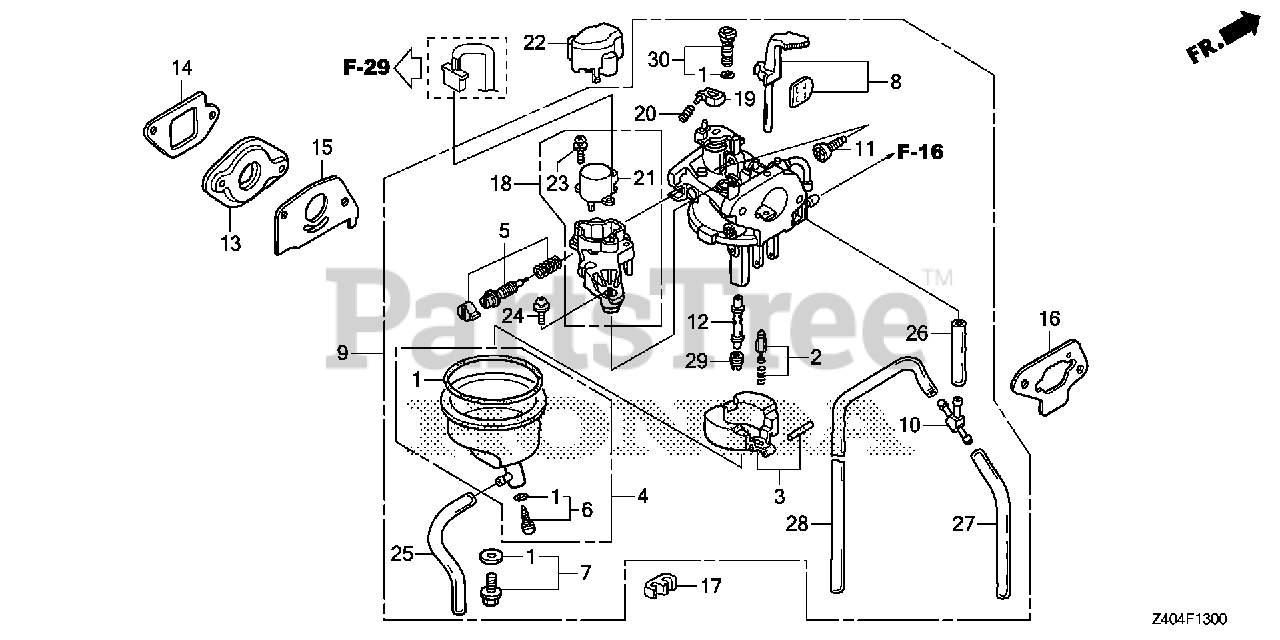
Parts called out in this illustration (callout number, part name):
1	GASKET SET (CARBURETOR NO.)
2	VALVE SET, FLOAT (CARBURETOR NO.) (SEAT NOT INCLUDED)
4	CHAMBER SET, FLOAT (CARBURETOR NO.)
5	SCREW SET (Honda Code 4219879). (CARBURETOR NO.)
6	SCREW SET, DRAIN (CARBURETOR NO.)
7	SCREW SET (CARBURETOR NO.)
9	CARBURETOR ASSY. (BF30C G)
10	JOINT, AIR VENT TUBE (CARBURETOR NO.)
11	SCREW, THROTTLE STOP
12	NOZZLE, MAIN (CARBURETOR NO.)
13	INSULATOR, CARBURETOR
14	GASKET, INSULATOR (ENGINE NO.)
15	GASKET, CARBURETOR
16	GASKET, AIR IN. JOINT
17	CLAMP D, IGNITION WIRE
18	MOTOR ASSY., THROTTLE CONTROL
19	LEVER, LINK (CARBURETOR NO.)
20	SPRING, COMPRESSION COIL (CARBURETOR NO.)
21	MOTOR, THROTTLE CONTROL (CARBURETOR NO.)
22	COVER, THROTTLE MOTOR
23	SCREW-WASHER (3X8)
24	SCREW-WASHER (4X10)
25	BULK HOSE, VINYL (3.5X6.5X8000) (9500(95003-05001-60M) (CARBURETOR NO.)
26	BULK HOSE, VINYL (4X7X8000) (95003-07(95003-07001-60M) (CARBURETOR NO.)
27	BULK HOSE, VINYL (4X7X8000) (95003-07(95003-07001-60M) (CARBURETOR NO.)
28	BULK HOSE, VINYL (4X7X8000) (95003-07(95003-07001-60M) (CARBURETOR NO.)
29	JET, MAIN (#52) Use from Engine SN BF12A B.
29	JET, MAIN (#55) Use from Engine SN BF22B D.
29	JET, MAIN (#58) Use from Engine SN BF22B D.
30	JET SET, PILOT (#35)
